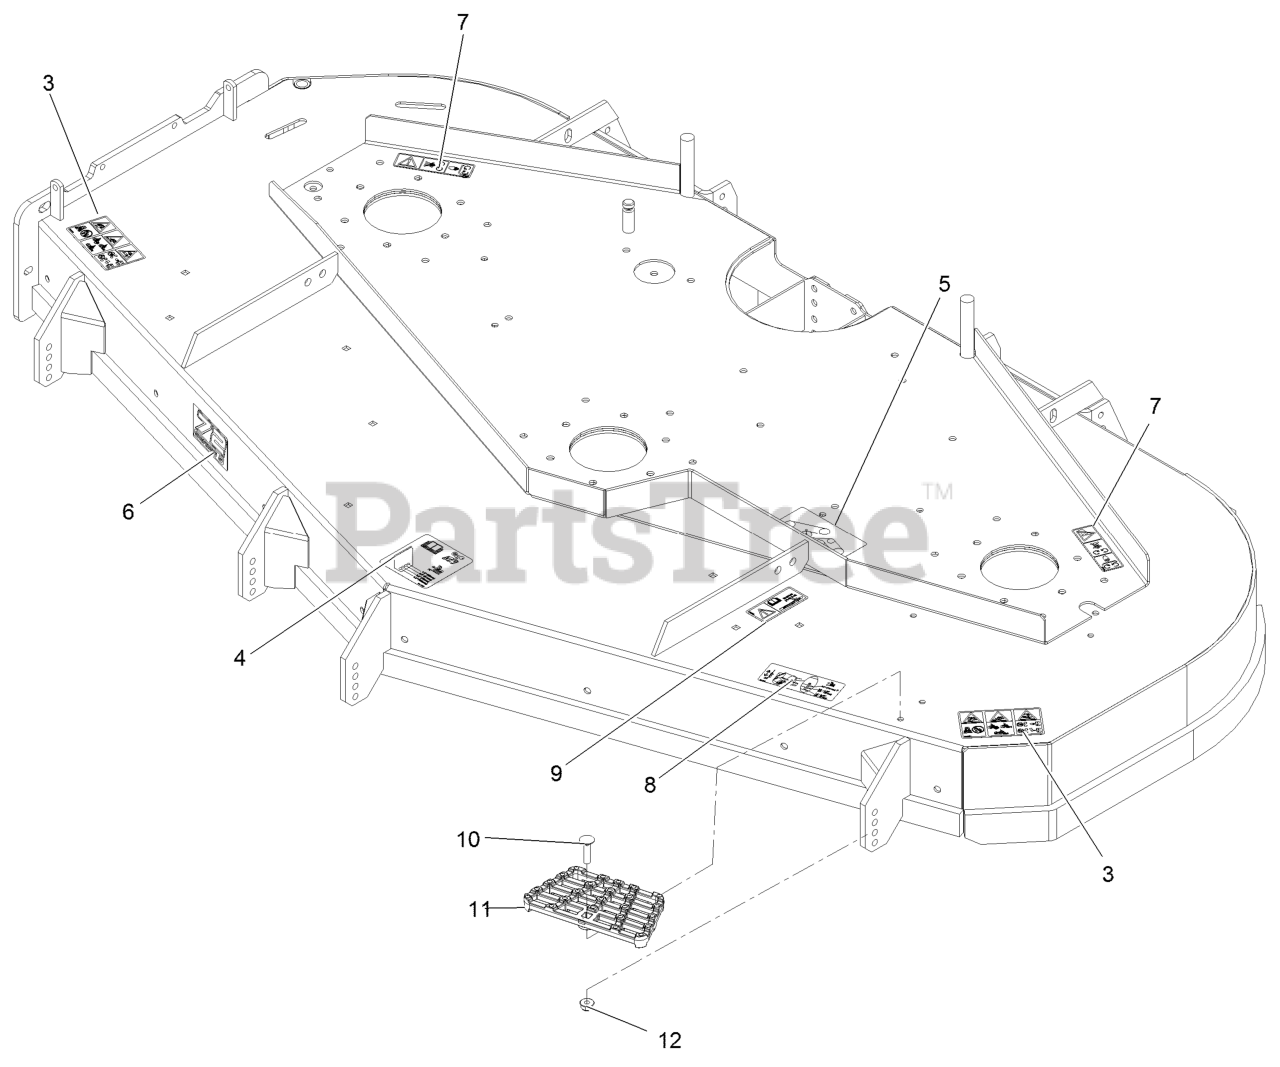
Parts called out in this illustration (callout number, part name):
3	DECAL-DANGER THROWN OBJECTS
4	DECAL-HEIGHT OF CUT
5	DECAL-BELT ROUTING
6	Decal, 725
7	DECAL-COVER, MISSING
8	DECAL-BAFFLE ADJ
9	DECAL-BOLT TORQUE
10	Bolt-Carriage 5/16-18 X 1 1/4
11	STEP-DECK
12	NUT-HF, NI
